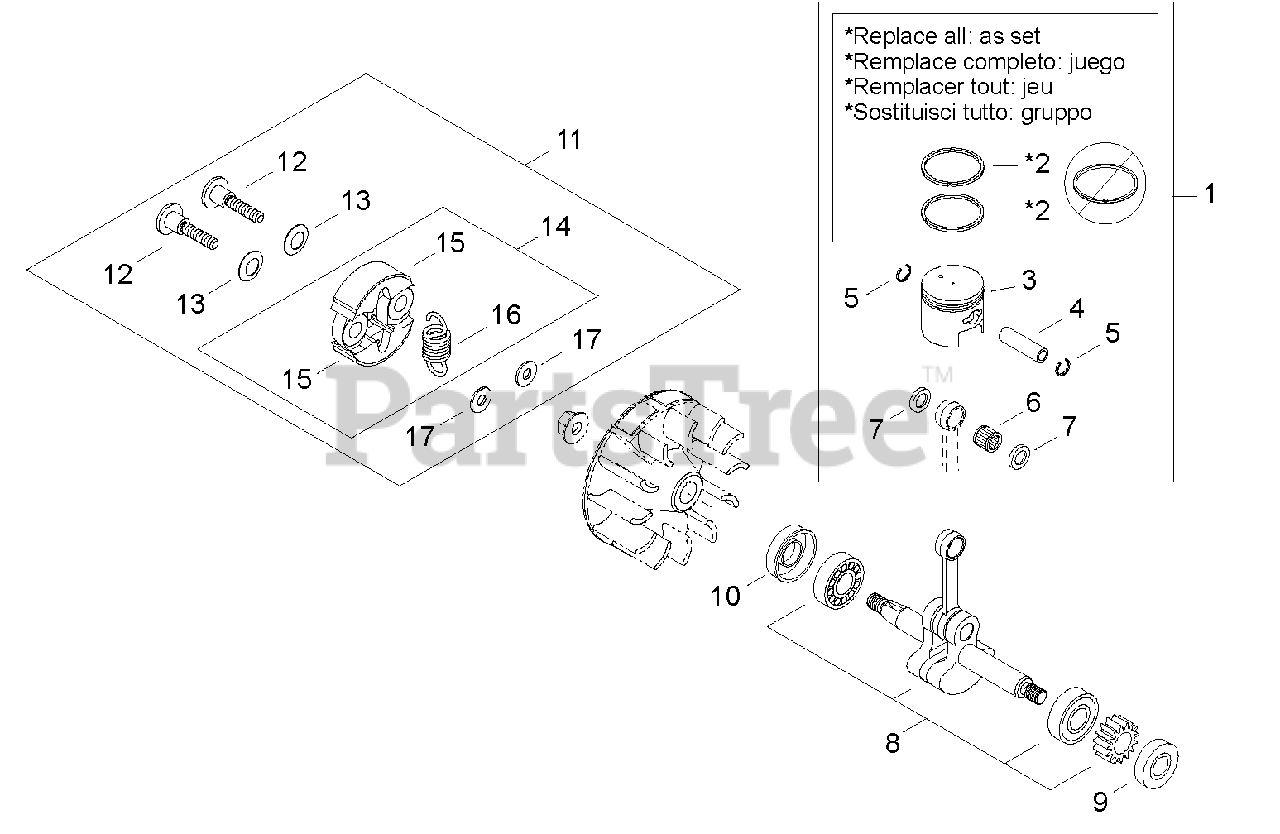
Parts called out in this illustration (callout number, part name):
1	PISTON KIT
2	RING, PISTON
3	PISTON
4	PIN, PISTON
5	RING, RETAINING
6	BEARING, NEEDLE
7	SPACER, PISTON
8	CRANKSHAFT ASSY
9	SEAL, OIL - 12
10	SEAL, OIL - 12
11	CLUTCH SHOE SET
12	BOLT, CLUTCH
13	WASHER - SPRING
14	CLUTCH ASSY
15	SHOE, CLUTCH
16	SPRING, CLUTCH
17	WASHER - 6
